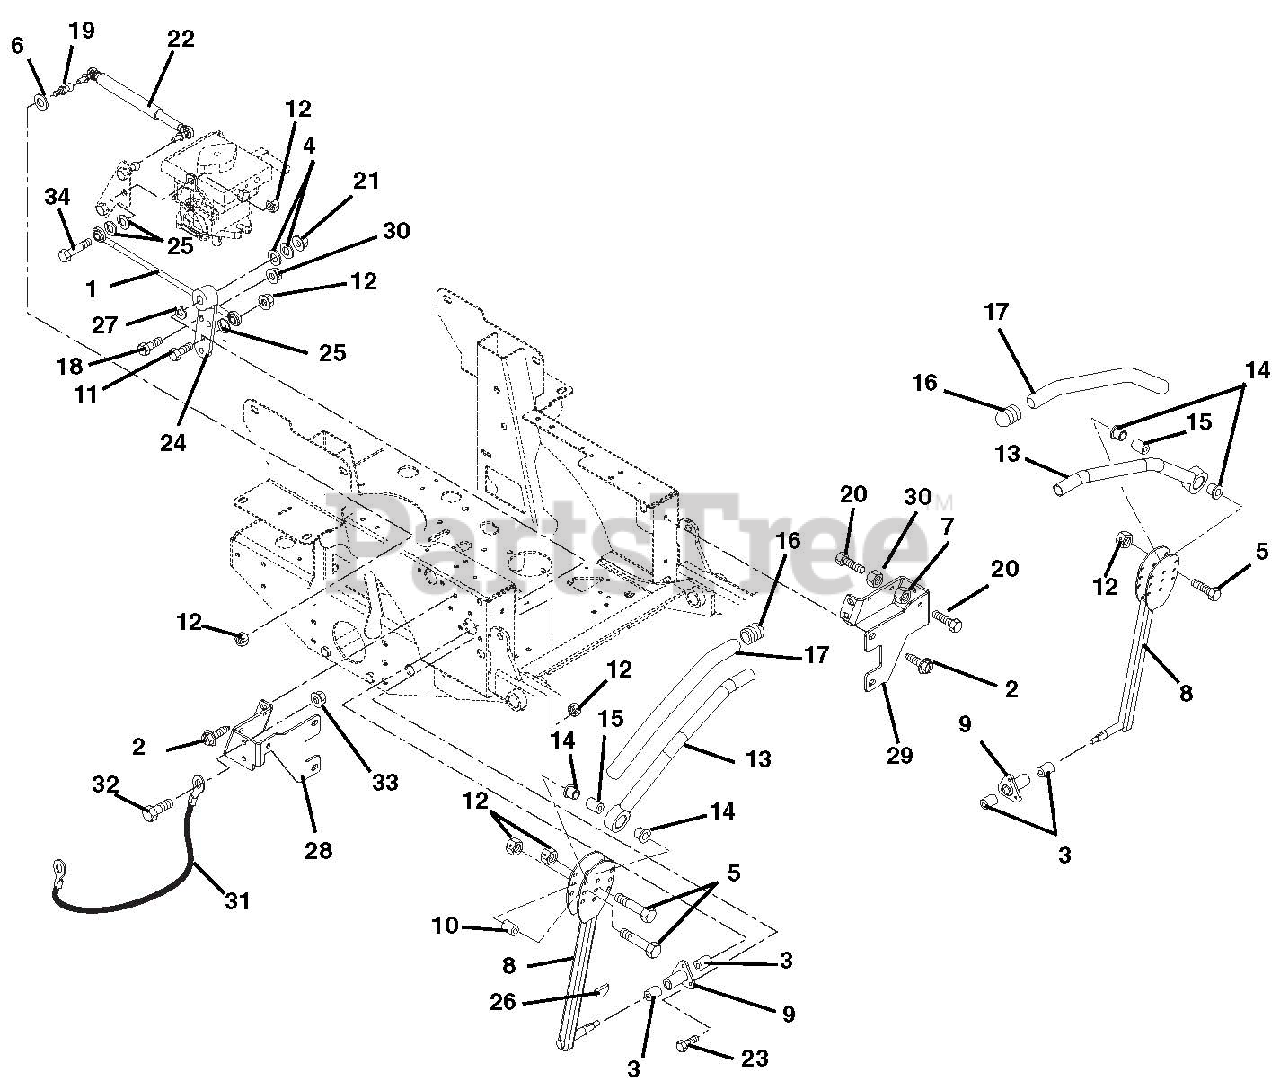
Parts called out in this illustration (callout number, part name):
1	Assembly, Steering Rod
2	Screw, Tapping .38-16 x .75 Hex Washer Head
3	Bushing .625 x .75 x .50
4	Washer, Flat Steel .406 x .812 x .065
5	Bolt, Hex .31-18 x 1.75 Grade 5
6	Washer, Flat Steel .38 x .875 x .083
7	Nut, Hex Jam .375-16
8	Control Arm
9	Housing, Bushing
10	Eccentric
11	Bolt, Hex .31-18 x 1.25 Grade 5
12	Nut, Nyloc Flange .375-16
13	Handle Weldment Left-Hand
13	Handle Weldment Right-Hand
14	Bushing, Flange Nylon .762 x 1.48 x .44
16	Caplug, Handlebar
17	Grip, Handlebar
18	Bolt, Hex .375-16 x 1.75
19	Stud, Ball
20	Bolt, Hex .38-16 x 1.25 Grade 5
21	Nut, Nyloc Flange 3/8-16
23	Bolt, Hex .31-18 x 1.00 Grade 5
24	Weldment, Pivot Arm
25	Washer, Locking .31 x .078 Regular
26	Key, Woodruff .13 x .63
27	Wave Washer
28	Stop, Steering-Right Hand
29	Stop, Steering-Left Hand
30	Nut, Locking Jam Center .375-16
31	Cable, Hood
32	Bolt-Hex .25-20 x .75 Grade 5
33	Nut, Nyloc Flange .25-20
34	Bolt, Hex .31-18 x 1.50 Grade 5
